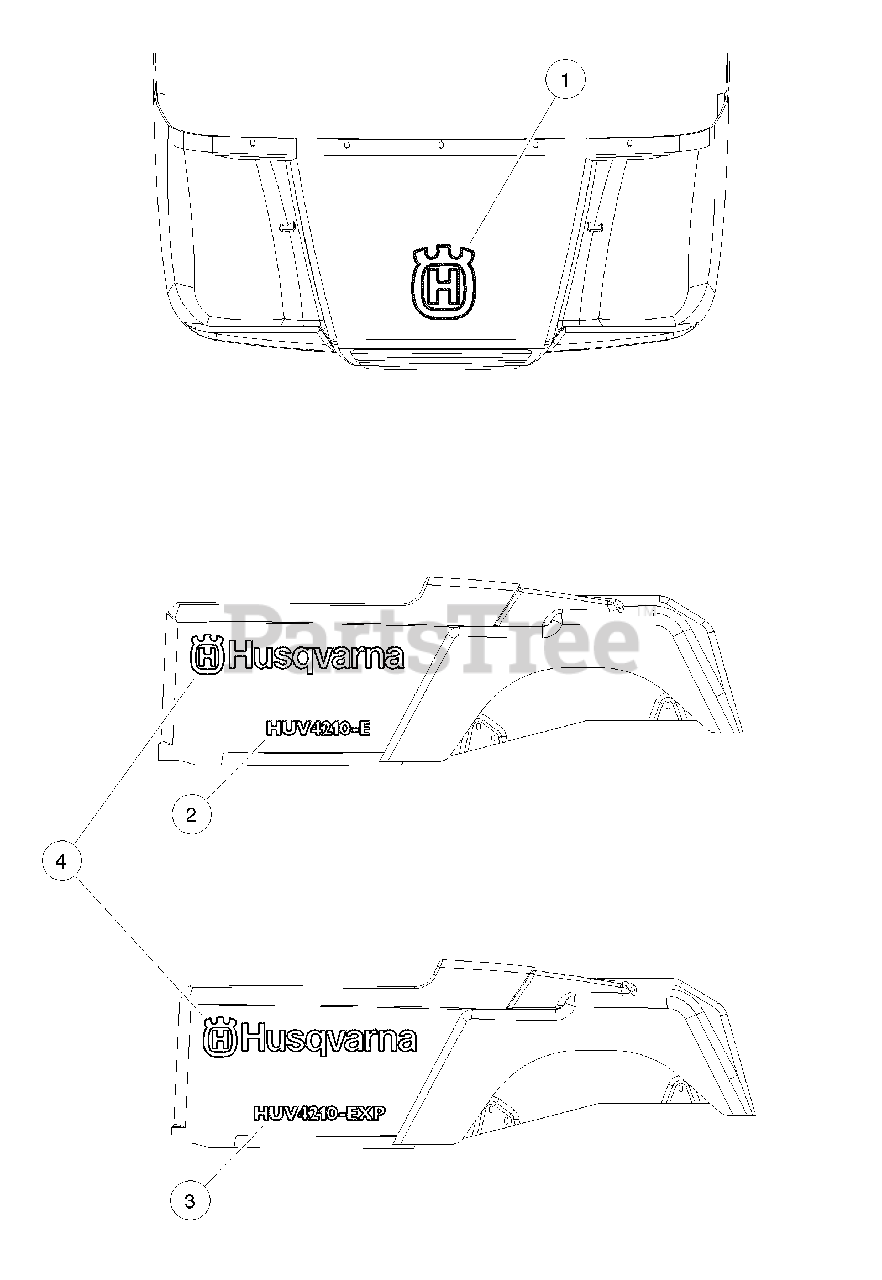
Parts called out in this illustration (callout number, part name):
1	Decal, Husqvarna, Cowl
2	Decal, Husqvarna, Side Panel
3	Decal, Husqvarna, Side Panel
4	Decal, Husq, Side
